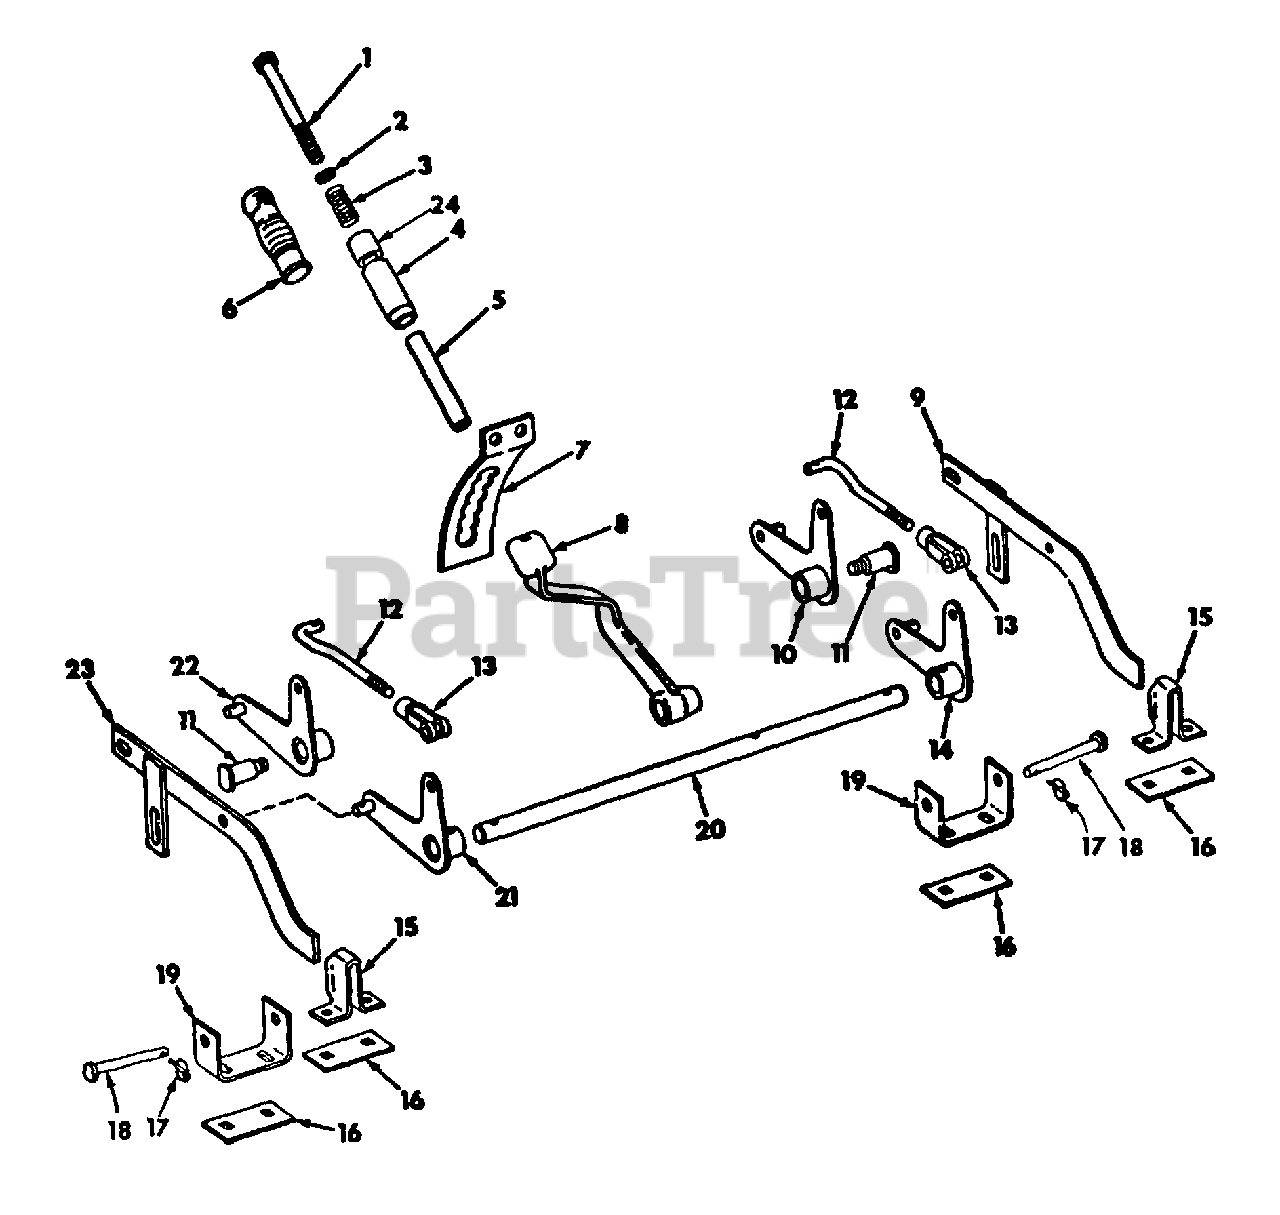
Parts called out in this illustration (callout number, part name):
1	SCREW, 3/8-16 X 6-1/4 C-Z HEX-HD CAP
2	WASHER, SPRING RETAINING
3	SPRING, COMPRESSION
4	BUSHING, MOWER LIFT HANDLE
5	BUSHING, LIFT HANDLE
6	GRIP, HANDLE
7	SECTOR, LIFT HANDLE
8	LEVER, MOWER LIFT
9	SUPPORT ASSY, LIFT BAR RH
10	ARM ASSY, MOWER LIFT FRONT RH
12	ROD, CONNECTING
13	CLEVIS, 3/8-24 X 2-3/16 SHORT ADJ ROD END
14	ARM ASSY, MOWER LIFT REAR RH
15	CHANNEL, LIFT BAR REAR GUIDE
16	PLATE, STIFFENER
17	PIN ASSY, KLIK
19	CLEVIS, LOCKPIN FRONT BRACKET
20	ROD, MOWER LIFT REAR
21	ARM ASSY, MOWER LIFT REAR LH
22	ARM ASSY, MOWER LIFT FRONT LH
23	SUPPORT ASSY, LIFT BAR LH
24	BUSHING, MOWER LIFT HANDLE
